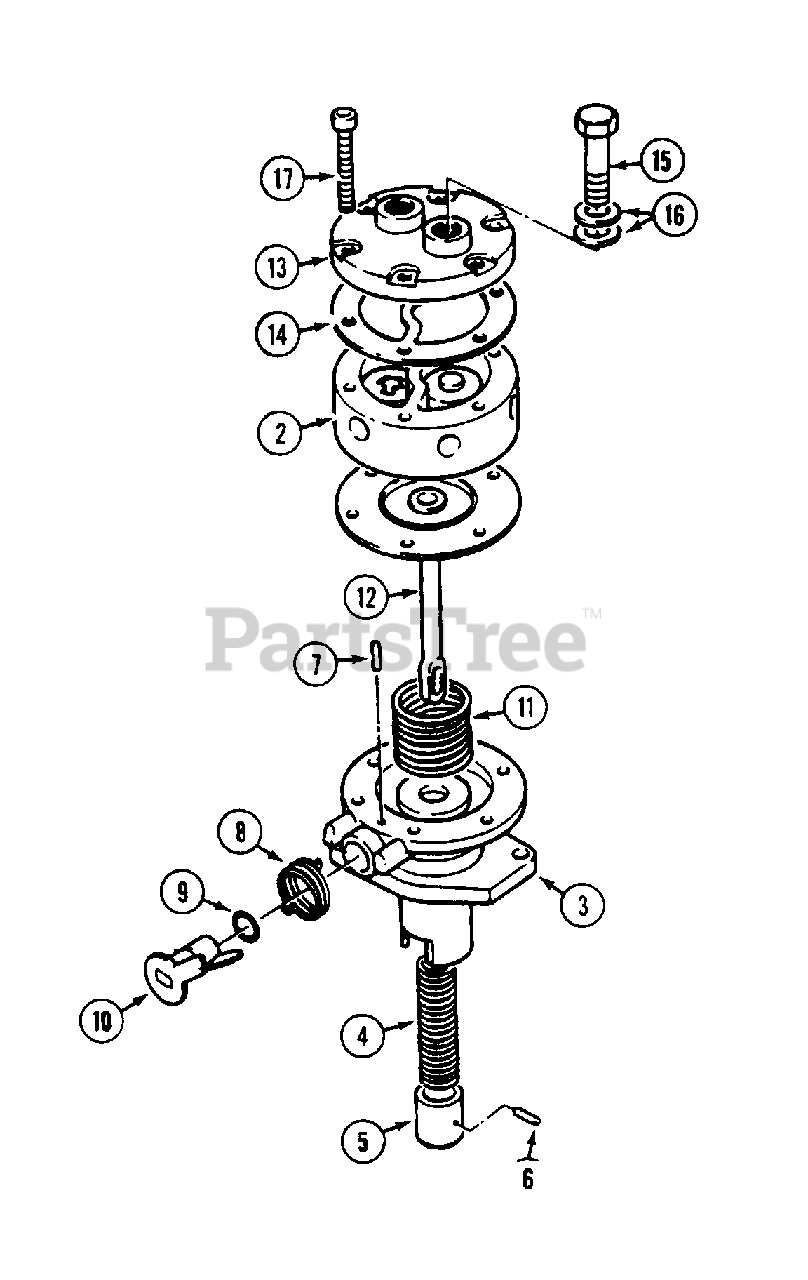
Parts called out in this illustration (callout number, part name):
2	BODY - upper
3	BODY - lower
4	SPRING
5	PLUNGER
6	PIN
7	PIN
8	SPRING
9	"O" RING
10	LEVER
11	SPRING
12	DIAPHRAGM
13	CAP
14	GASKET
15	BOLT
16	WASHER
17	SCREW
